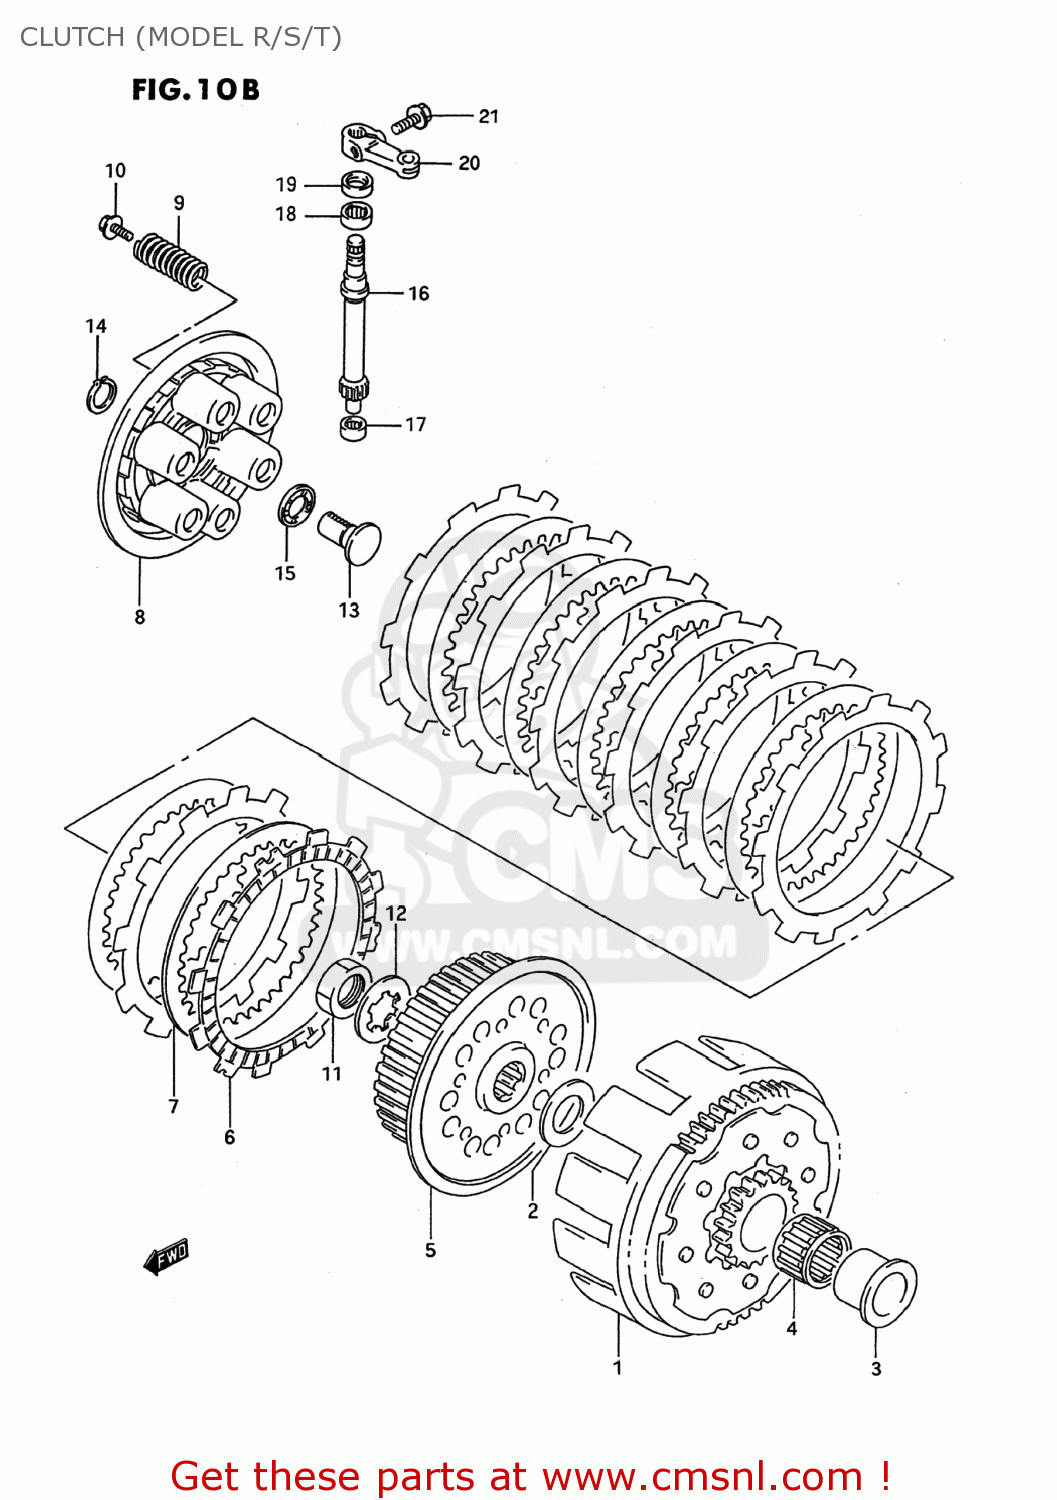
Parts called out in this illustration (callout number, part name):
1	GEAR ASSEMBLY,PRIMARY DRIVE
2	WASHER(22X38X2)
3	SPACER,PRIMARY DRIVEN GEAR
4	BEARING(29X34X21.8)
5	HUB,CLUTCH SLEEVE
6	PLATE,CLUTCH DRIVE (NAS)
7	PLATE,CLUTCH DRIVEN T: (NAS)
8	DISC,CLUTCH PRESSURE
9	SPRING
10	BOLT(5X25)
11	NUT
12	WASHER,LOCK
13	RACK,CLUTCH RELEASE
14	CIRCLIP,10MM
15	BEARING(10X22X2.8)
16	PINION,CLUTCH RELEASE(NT:12)
17	BEARING(9X13X10)
18	BEARING(12X16X10)
19	SEAL,OIL(10X17X5)
20	ARM,CLUTCH RELEASE
21	BOLT
